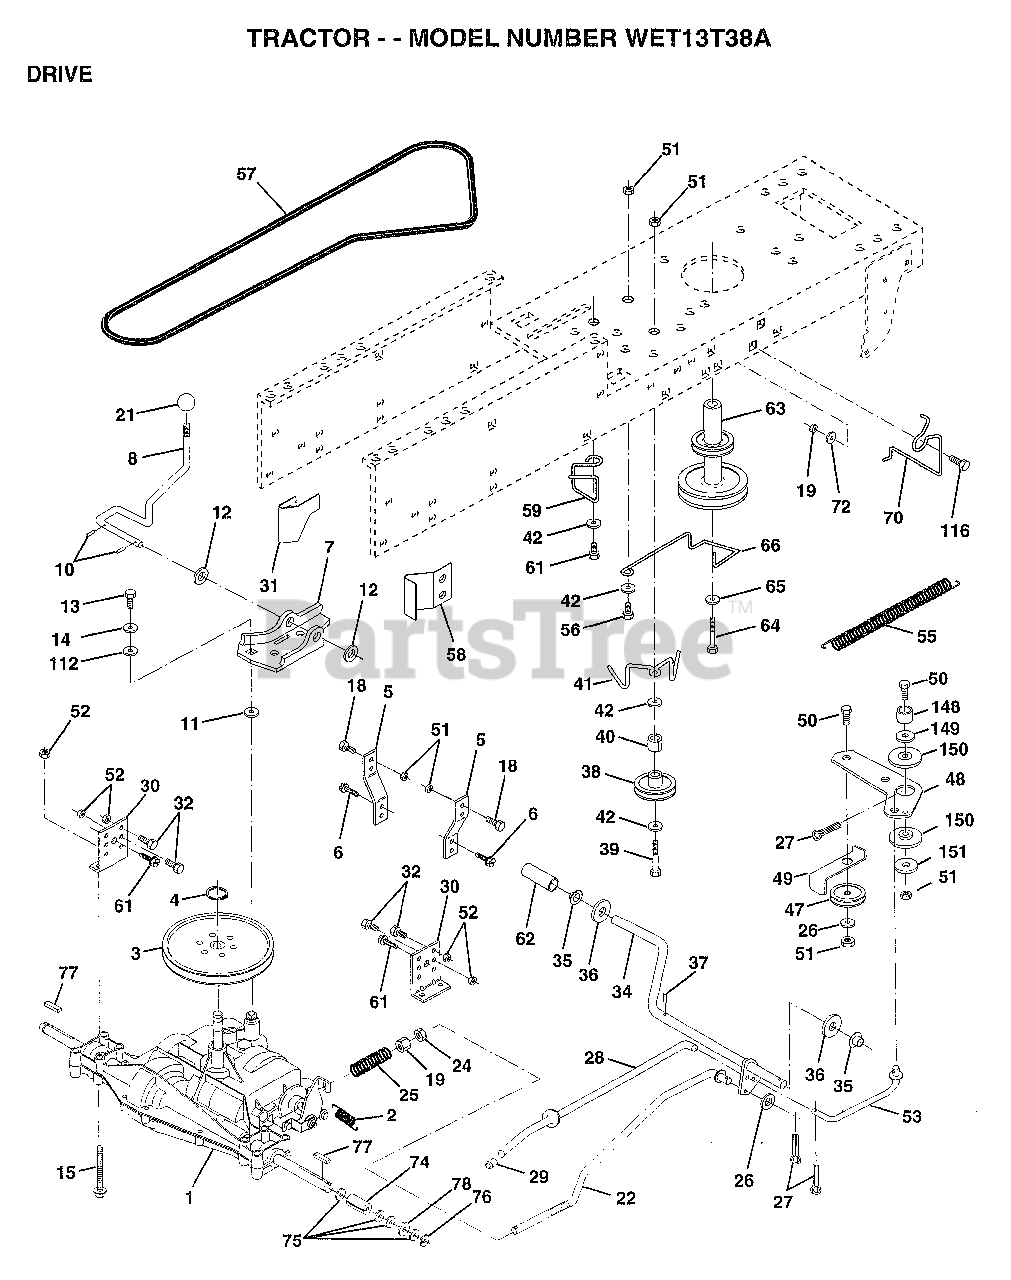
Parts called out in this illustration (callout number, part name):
2	SPRING.BRAKE.RETU
3	PULLEY TRANS
5	STRAP TORQUE
6	SCREW
7	BRKT.SADDLE.SHIFT
8	SHIFT ROD
10	PIN COTTER 1/8
11	WASH-SHFT PLT LT
12	WASHER
13	BOLT.1/4-28.W/PAT
14	LOCKWASHER
15	BOLT.HX.FLG.5/16
18	BOLT
19	NUT
21	KNOB T (1/2-HOLE)
22	BRAKE ROD
24	NUT
25	SPRING ROD LT
26	WASHER
27	COTTER PIN
28	ROD.BRAKE.PARK.LT
29	PLUNGER CAP T
30	TRANSAXLE MTG BKT
31	"KEEPER,BELT LH T"
32	BOLT
34	SHAFT ASM-PEDAL F
35	NYLON BEARING
36	WASHER LT
38	PULLEY.IDLER.FLAT
39	BOLT
40	SPACER T
42	WASHER
48	BELLCRANK.CLUTCH
49	RETAIN BELT
53	"LINK, CLUTCH T"
55	"SPRING, RETURN LT"
58	"KEEPER,BELT RH T"
59	KEEPER BELT CNTSP
61	SCREW
62	PEDAL COVER T
63	PULLEY.ENGINE
64	BOLT
65	LOCKWASHER
66	KEEPER-BELT
70	KEEPER BELT ENG
72	WASHER
74	SPACER LT
76	E-RING LT
77	SQUARE KEY
78	WASHER
112	WASHER LT
116	BOLT RDHD 3/8-16
149	SPACER RETAINER
150	BUSHING.NYLON
151	WASHER
